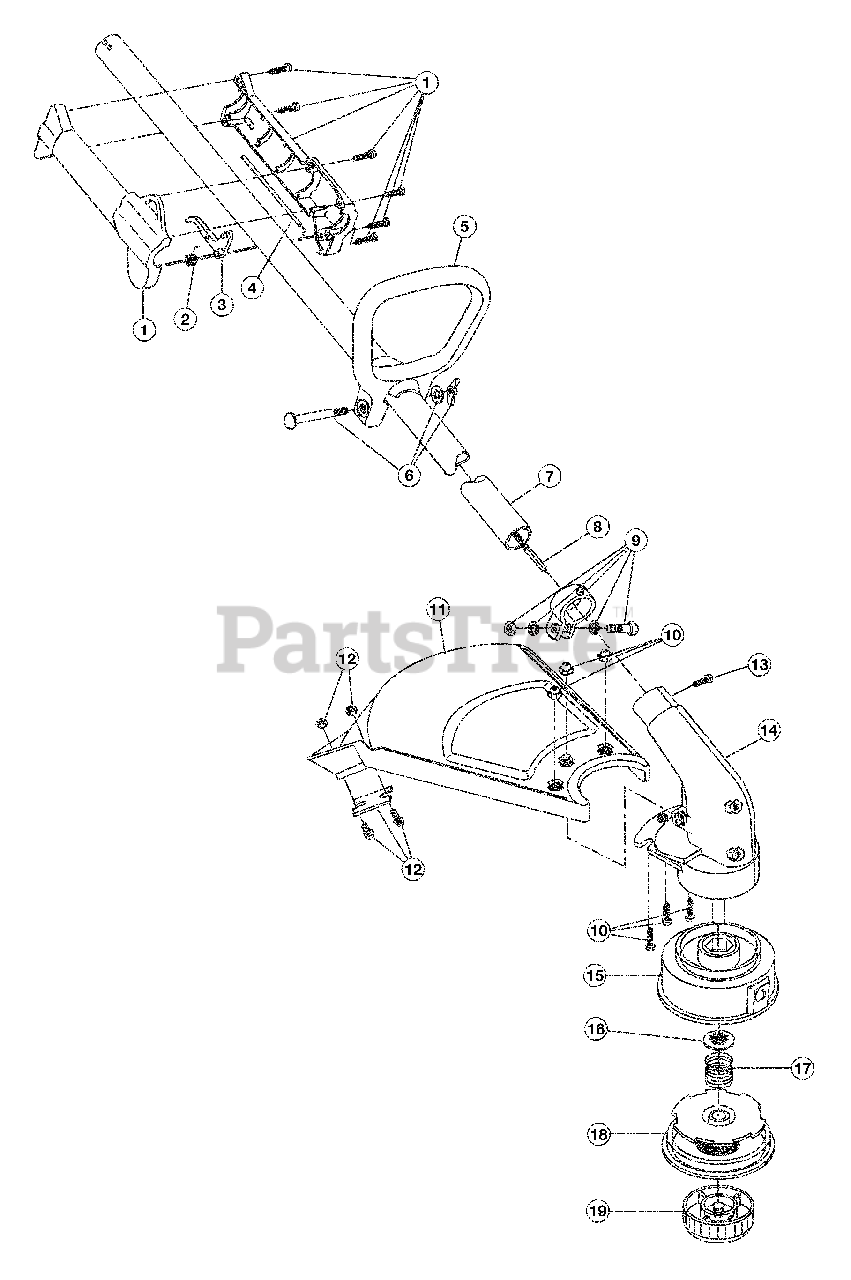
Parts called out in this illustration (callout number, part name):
1	Throttle Housing Assembly
2	Throttle Trigger Spring
3	Throttle Trigger
4	Throttle Cable
5	D-Handle Assembly
6	D-Handle Hardware
7	Drive Shaft Housing Assembly
8	Flexible Drive Shaft
9	Lower Clamp Assembly
10	Guard Mounting Hardware
11	Guard Assembly
12	Blade Assembly
13	Anti-Rotation Screw
14	Gearbox Assembly
15	Outer Spool Assembly
16	Retainer
17	Spring
18	Inner Reel
19	Bump Head Knob Assembly
